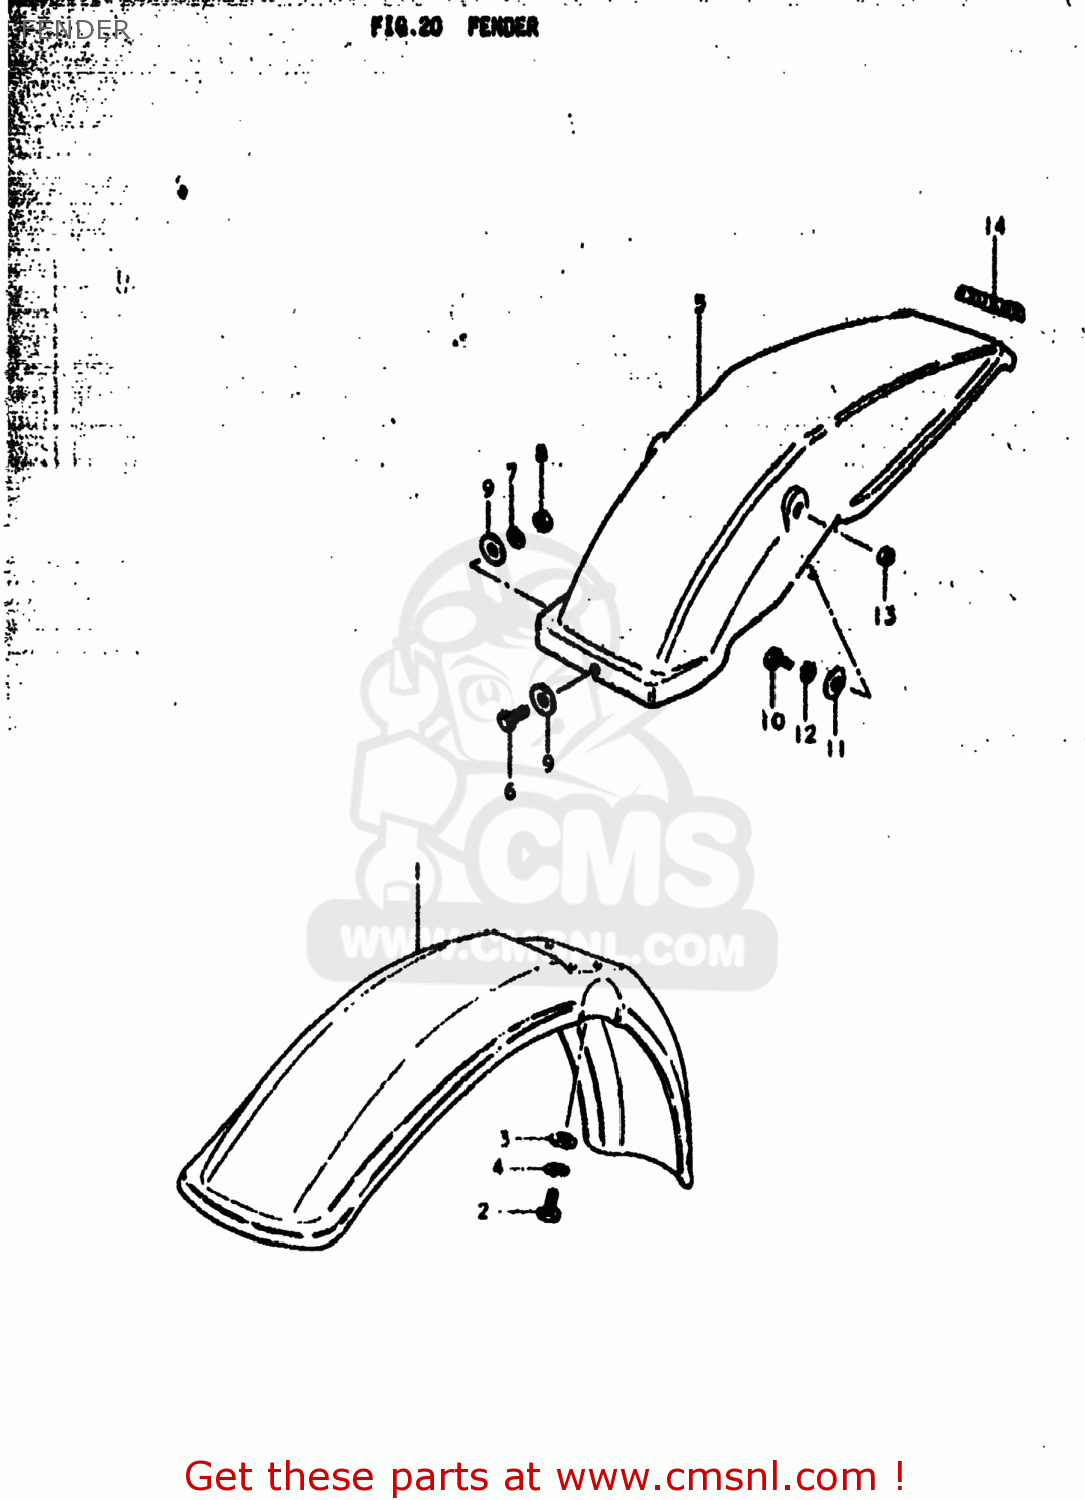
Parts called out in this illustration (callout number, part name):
1	FENDER,FRONT
2	BOLT, UPPER
3	SPACER
4	LOCK WASHER
5	FENDER,REAR
6	BOLT, UPPER
7	LOCK WASHER
8	NUT
9	WASHER
10	BOLT, UPPER
11	WASHER
12	LOCK WASHER
13	NUT 6MM
14	EMBLEM,FRONT FENDER
